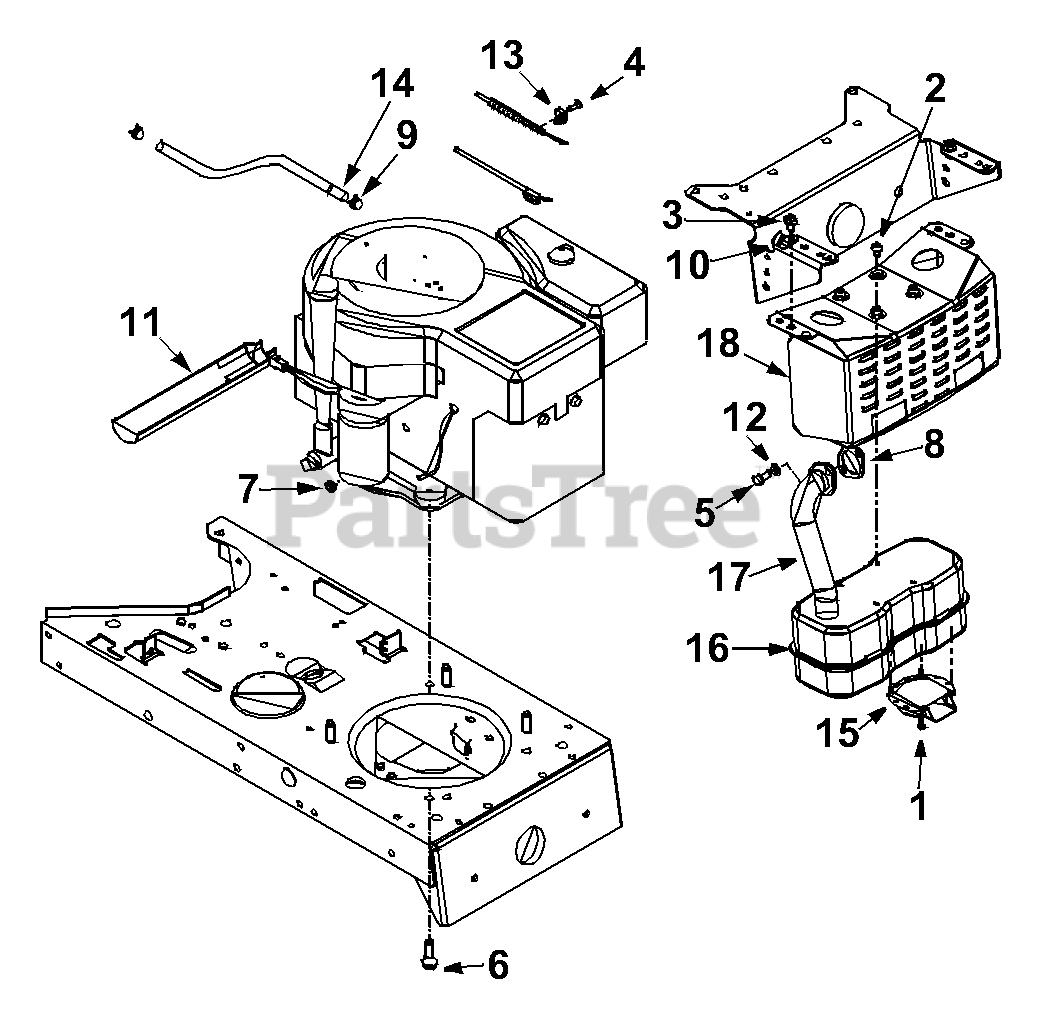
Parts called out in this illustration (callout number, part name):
1	Hex Tap Scr. #8-32 x .38" Lg.
2	Hex TT-Tap Scr. 1/4-20 x .5" Lg.
3	Hex TT-Tap Scr. 5/16-18 x .62"
4	Hex Wash. Scr. #10-32 x .62"
5	Socket Head Scr. 5/16-18 x .62"
6	Hex TT-Tap Scr. 3.8-16 x 1.25"
7	Hex Sems Scr. 1/4-20
8	Gasket
9	Hose Clamp
10	Clamp
11	Oil Drain Sleeve
12	Lock Washer 5/16 I.D.
13	Casing Clamp
14	Fuel Line
15	Muffler Deflector
16	Muffler
17	Exhaust Pipe
